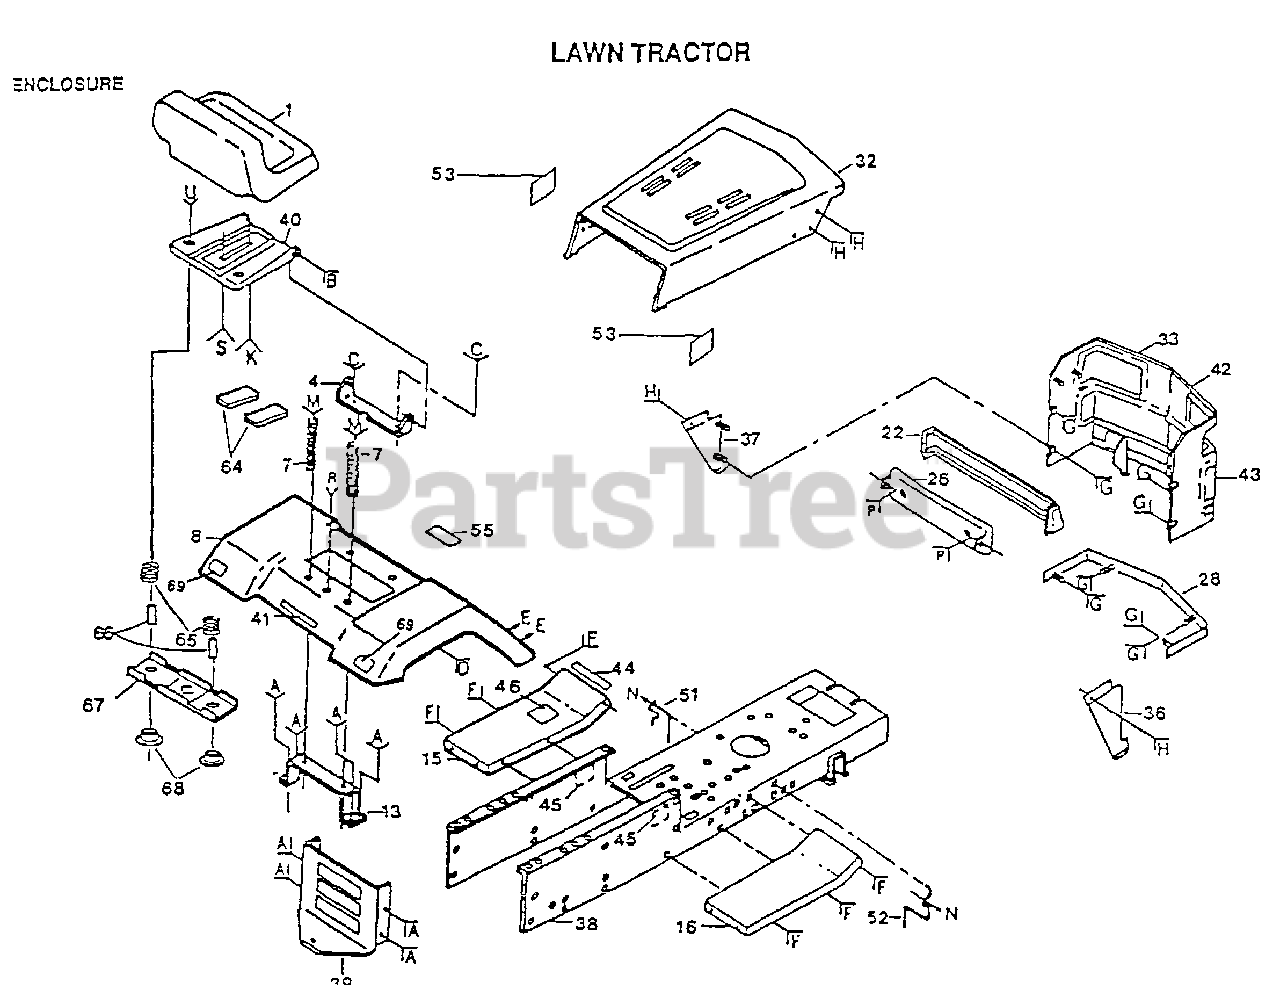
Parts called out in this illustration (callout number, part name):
7	SPRING COMPRESSIO
15	FOOTREST LH
16	FOOTREST
38	CHASSIS ASS'Y
44	DECAL T
45	"DECAL,CHASSIS"
51	BELT GUIDE
52	BELT GUIDE
64	STRIP FORM
65	SPRING
66	SPACER SPLIT
67	BRKT SWITCH
68	BUSHING
69	REFLECTOR-TAIL YT
